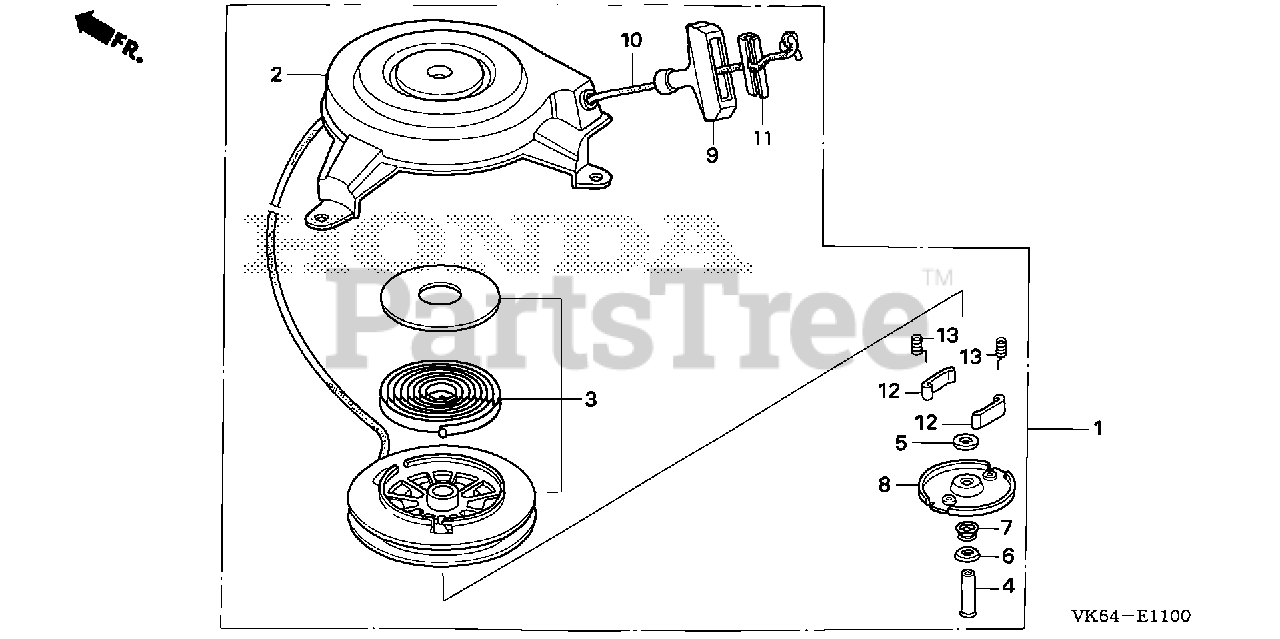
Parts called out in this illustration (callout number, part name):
1	STARTER ASSY., RECOIL
2	HOUSING ASSY. (NA USE ALT:28400-ZG9-803)
3	PULLEY & SPRING ASSY.
4	PIN, CENTER
5	PLATE A, FRICTION
6	PLATE B, FRICTION (NOT AVAILABLE)
7	SPRING, FRICTION
10	ROPE (#5.5X55")
11	HANDLE, REINFORCEMENT
12	RATCHET, STARTER
13	SPRING, DOG
